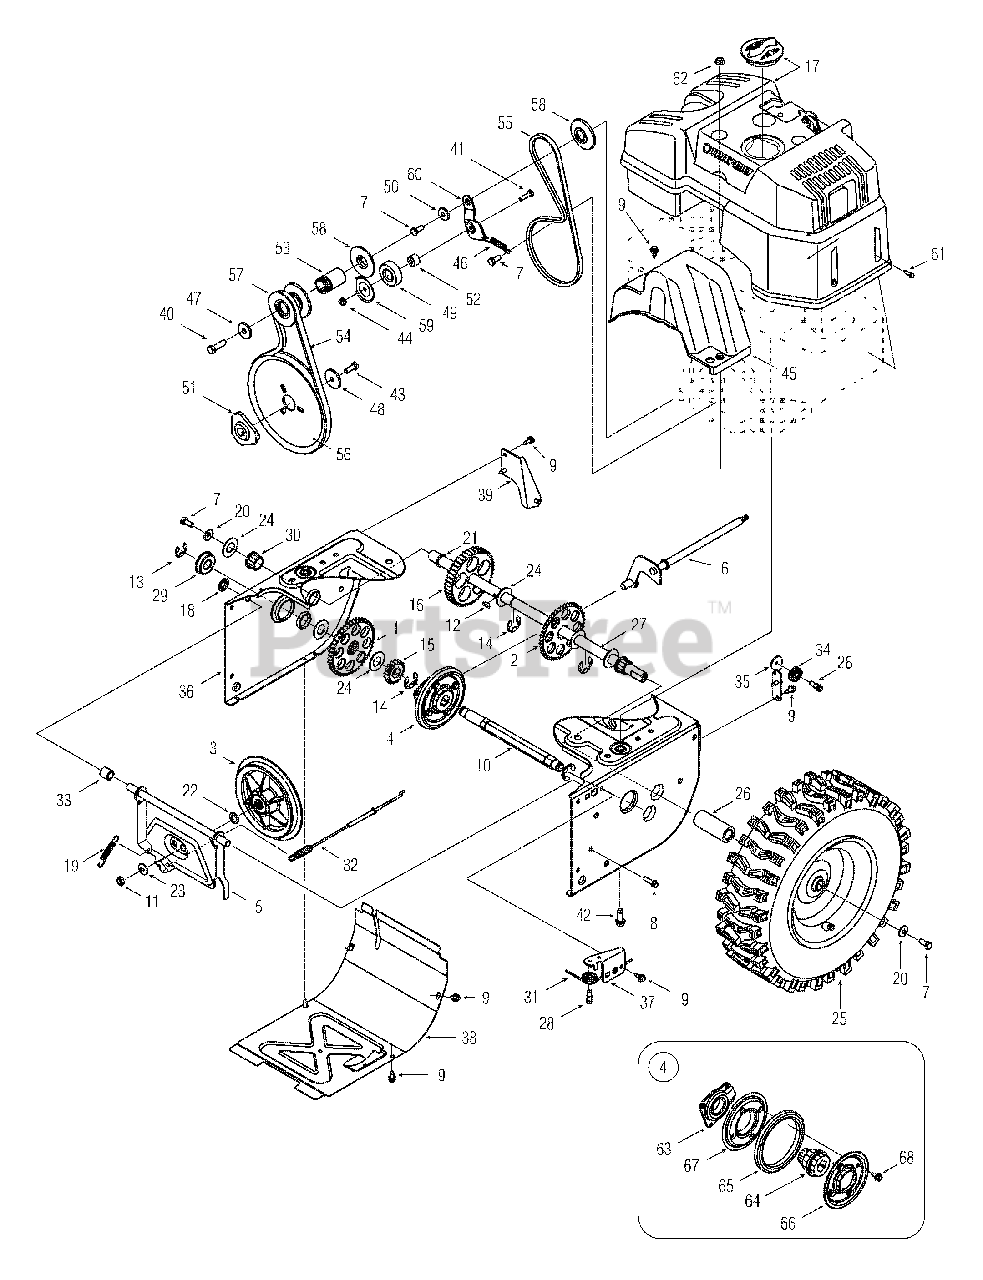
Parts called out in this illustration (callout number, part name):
1	Gear Assembly, 16/4 4T
2	Gear Assembly, 16/4 4T
3	Disc Assembly , Friction Wheel .375 x 6.75
4	Wheel Assembly, Friction, 4.9 OD
5	Support Bracket Ass'y, Friction Wheel
6	Shift Assembly, Rod
7	Screw, 5/16-24 x .7 50, Gr5
8	Screw, 1/4-20x 1.000
9	Screw, 1/4-20x .625
10	Hex Shaft, Drive, .75
11	Nut, Jam, 3/8-24, Gr2
12	Key, Hi-pro 3/16x 5/8
13	Ring, E Type, .750
14	Ring, E-Type, .875
15	Pinion, 16T
16	Gear, 44T
17	Shroud Assembly, Troy-Bilt
18	Nut, Speed, .500
19	Extension Spring
20	Washer, Bell, .340 x .872 x .060
21	Washer, Flat, .75 x 1.00 x .060
22	Washer, Flat, .406 x .875 x .059
23	Washer, Bell, .375 x .870 x .063
24	Washer, Flat, .793 x 1.24 x .060
26	Spacer, 1.25 OD x .75 ID x 3.00
27	Axle, .75 x 22
28	Screw, 1/4-28 x .375
29	Bearing, Ball, 17 x 40 x 12
30	Bearing, Hex Flange x .75 ID
31	Cable, Auger, 44.75
32	Cable, Drive, 41.75
33	Spacer, .508 ID x .75 OD x .68
34	Roller, Cable
37	Guide Bracket, Front, Auger Cable
38	Cover, Frame
39	Roller Bracket, Drive Cable
40	Screw, 3/8-24x 1.25, Gr8
41	Screw, 1/4-20x 1.00, Gr5
42	Screw, Sems, 3/8-16 x 1.00
43	Screw, 5/16-24 x .875, Gr8
44	Nut, Flange Lock, Nylon, 1/4-20, Gr F
45	Cover, Belt
46	Spring, Extension, .3 8 OD x 2.68
47	Washer, Flat, .406 x 1.25 x.157
48	Washer, Flat, .34 x 1.50 x .1 50
49	Bearing, Ball, 20 x 47 x 14
50	Shoulder Spacer
51	Pulley, Adapter, .75 Dia.
52	Spacer, .777 OD x .2 60 ID x.550
53	Spacer, .875 ID x 1.185 OD
54	V-Belt, 1/2"
55	V-Belt, 3/8"
56	Pulley, Auger, 8.1 x .50
57	Pulley, Half, 2.600 OD
58	Pulley, Half, 2.2 OD
59	Washer, Bearing, 2.12 OD x .255 ID
60	Idler, Bracket, Drive
61	Screw, #10-16 x .75
62	Nut, Flange Lock, 5/16-18, Gr5
63	Bearing Assembly , Friction Wheel
64	Hub, Friction Wheel
65	Friction Wheel Rubber, 4.875 OD
66	Plate, Friction, 12 Pt 4.60 Dia
67	Plate, Friction, Extrs, 12 Pt 4.60 Dia
68	Screw, Self-tapping, 1/4-14 x 0.625
